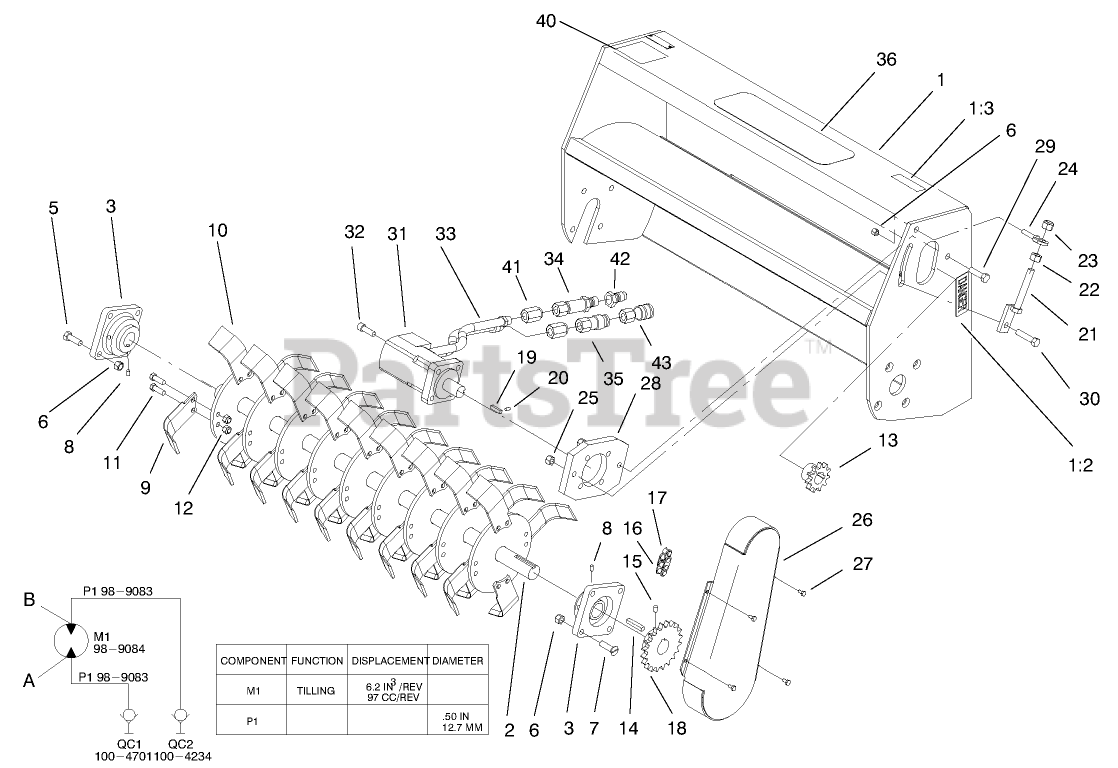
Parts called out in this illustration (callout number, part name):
1	TILLER FRAME ASM
1:2	DECAL-DANGER
1:3	DECAL-WARNING
2	SHAFT-TINE
3	BEARING ASM
5	SCREW-HH
6	NUT-LOCK, NI
8	SCREW-SET
9	Tine-RH
10	Tine-LH
11	SCREW-HH
12	NUT-LOCK, INSERT
13	SPROCKET-11 TOOTH
14	KEY-SQUARE
15	SCREW-SET
16	CHAIN-ROLLER
17	LINK-CONNECTING
18	SPROCKET-20 TOOTH
19	KEY-SQUARE
20	SCREW-SET
21	CHAIN ADJUSTMENT ASM
22	NUT-HEX
23	NUT-LOCK NI
24	HOLDER-ADJUSTMENT
25	NUT-LOCK, NI
26	COVER-CHAIN, TILLER
27	SCREW-HH
28	PLATE-MOUNT, MOTOR
29	SCREW-HH
30	SCREW-HH
31	MOTOR-HYD
32	SCREW-HSH
33	HOSE - HYDRAULIC
34	NIPPLE-CONNECT, PRESSURE
35	COUPLER-FACE, FLUSH
36	DECAL-DINGO, FRONT
40	DECAL
41	ADAPTER-HYD
42	DISCONNECT-QUICK, MALE
43	DISCONNECT-QUICK, FEMALE
